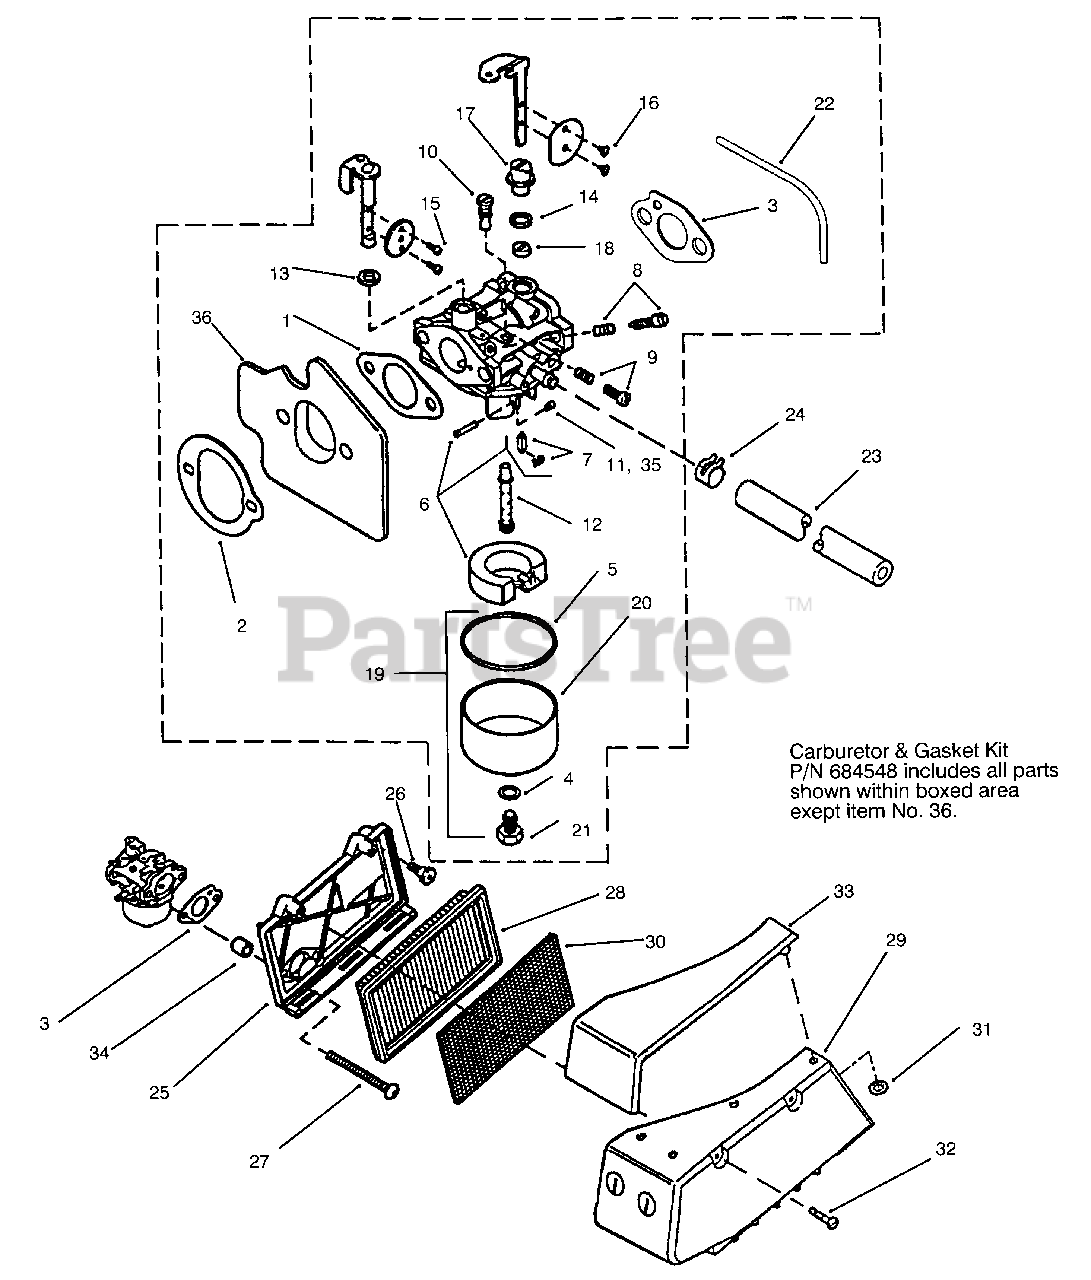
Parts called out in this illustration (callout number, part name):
1	Gasket-Carb. to Spacer
2	Gasket-Spacer to Engine
3	Gasket-Air Filter Base
4	Gasket-Bowl Retainer
5	Gasket-Fuel Bowl
6	Kit-Float & Needle (Incl. Ref. No. 7)
7	Needle and Clip
8	Kit-Idle Needle & Spring
9	Kit-Idle Speed
10	Pilot Jet
11	Main Jet
13	Seal-Throttle Shaft
14	Seal-Choke Shaft
15	Screw-Throttle Valve
16	Screw-Choke Valve
17	Pivot-Upper Choke Shaft
18	Pivot-Lower Choke Shaft
19	Kit-Bowl (Incl. Ref. No. 20-21)
20	Bowl-Fuel
21	Screw-Bowl Retainer
22	Hose-Carb Vent
23	Gas Line
24	Clamp-Hose
25	Base-Air Filter
27	Screw-Carb. to Engine
28	Filter-Air
29	Assembly-Cover, Air Filter (Incl. Ref No. 30-33)
30	Pre-Filter
31	Pushnut
33	Cover-Air Box
35	Main Jet-High Altitude (Over 3,500 Feet)
36	Assy.-Spacer & Oil Nozzle
